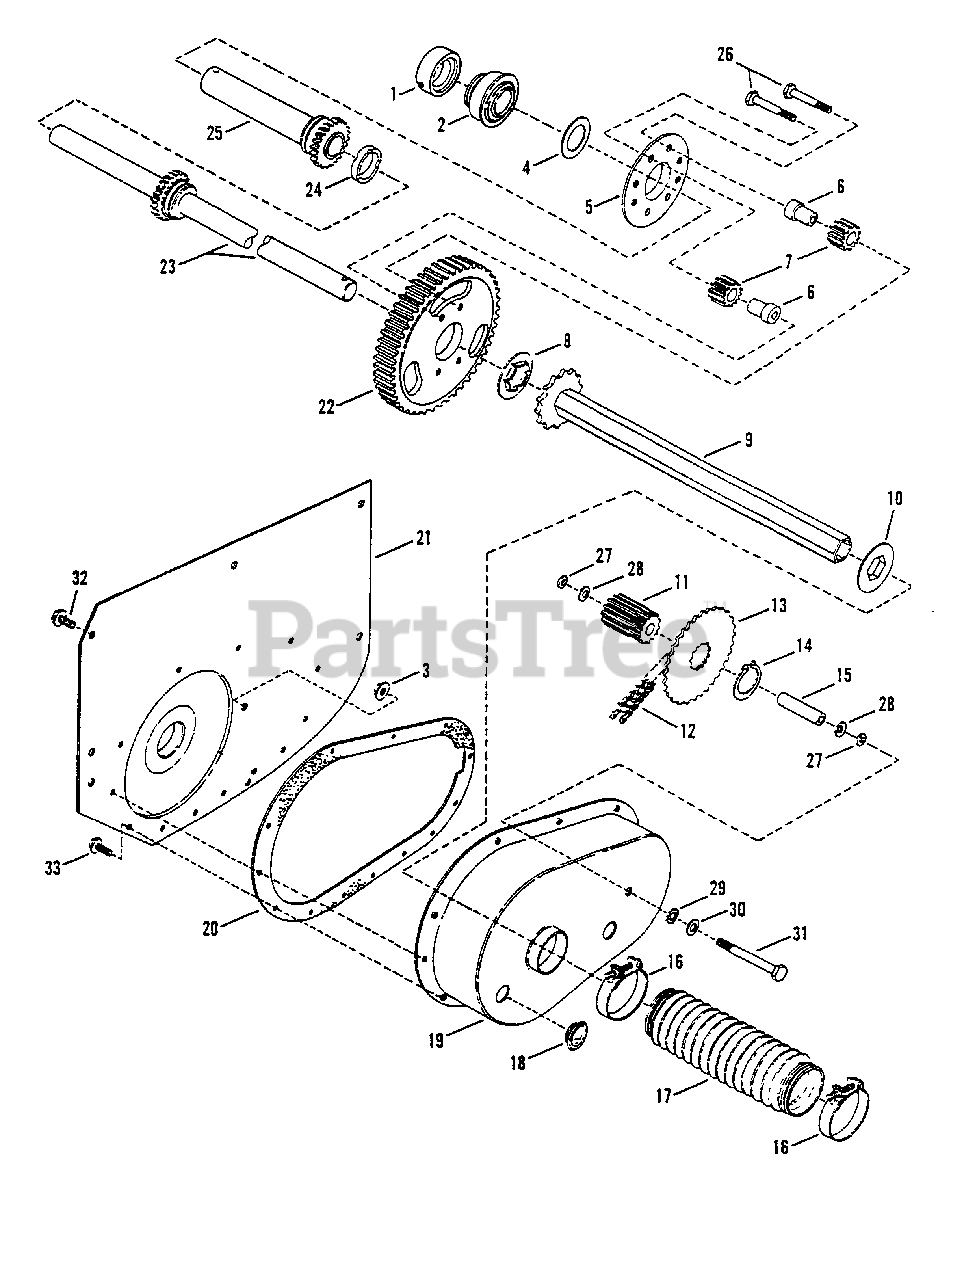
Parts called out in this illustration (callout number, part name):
1	COLLAR, Lock
2	BEARING, Axle (Right Hand Fender)
3	NUT, 5/16-24 Hex Flange Lock
4	WASHER, Thrust
5	PLATE, Differential
6	SPACER, Pinion
7	GEARS, Differential Pinion
8	WASHER, Thrust
9	ASSEMBLY, Drive Hex Tube
10	WASHER, Hex Insert
11	GEAR, 11 Teeth-10 Pitch
12	CHAIN, 46 Pitch (#35)
13	SPROCKET
14	RING, Retaining
15	SPACER
16	CLAMP, Boot
17	BOOT, Oil Seal
18	PLUG, Oil Fill & Check
19	CASE, Transmission
20	GASKET, Transmission Case
21	FENDER, Right Hand (2.498" bearing hole)
22	GEAR, 63 Teeth-10 Pitch
23	AXLE, Long
24	SPACER, Differential (1.25" ID x .425 Wide)
25	AXLE, Short
26	SCREW, 5/16-24 x 1-5/8" Hex Cap Special Lock 4
27	O-RING, 5/16"
28	WASHER, Belleville
29	WASHER, 5/16 External Tooth Lock
30	WASHER, 5/16 Flat
31	BOLT, 5/16-24 x 2-5/8" Idler
32	SCREW, 5/16-18 x 5/8" Self-Tapping
33	SCREW, 1/4-20 x 5/8" Self-Tapping
